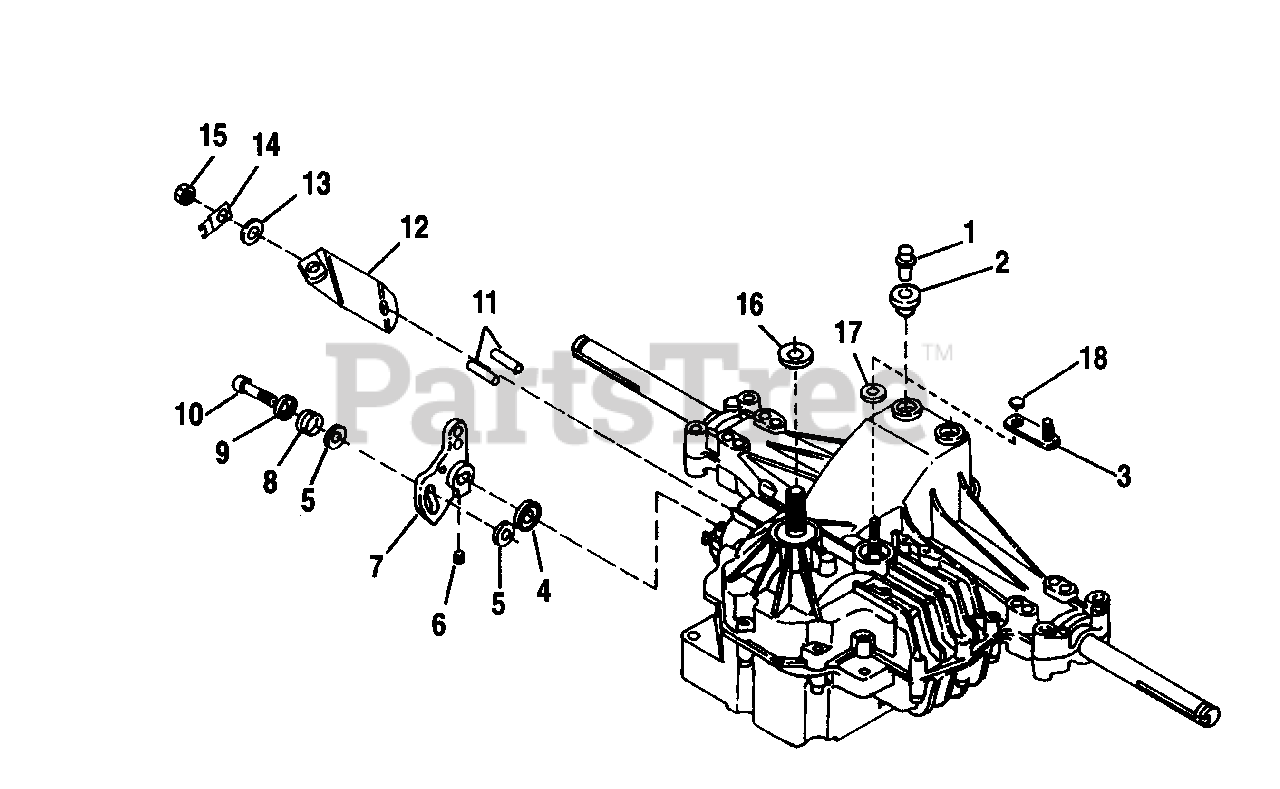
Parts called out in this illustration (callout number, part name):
1	* BREATHER ASSY.
2	* BUSHING, Rubber
3	* ARM, Bypass
5	* PUCK, Dampener
6	* SET SCREW
7	* ARM, Control
9	* CUP WASHER
10	* SCREW, Socket Hd.
11	* ACTUATOR PIN
12	* ARM, Brake
13	* WASHER, 7/16 x 7/8 x 1/16
14	* LOCKING STRAP
15	* NUT, Hex, Lock, 5/16 x 24
16	* SEAL, Lip
17	* SEAL, Lip
18	* RING, Retaining
